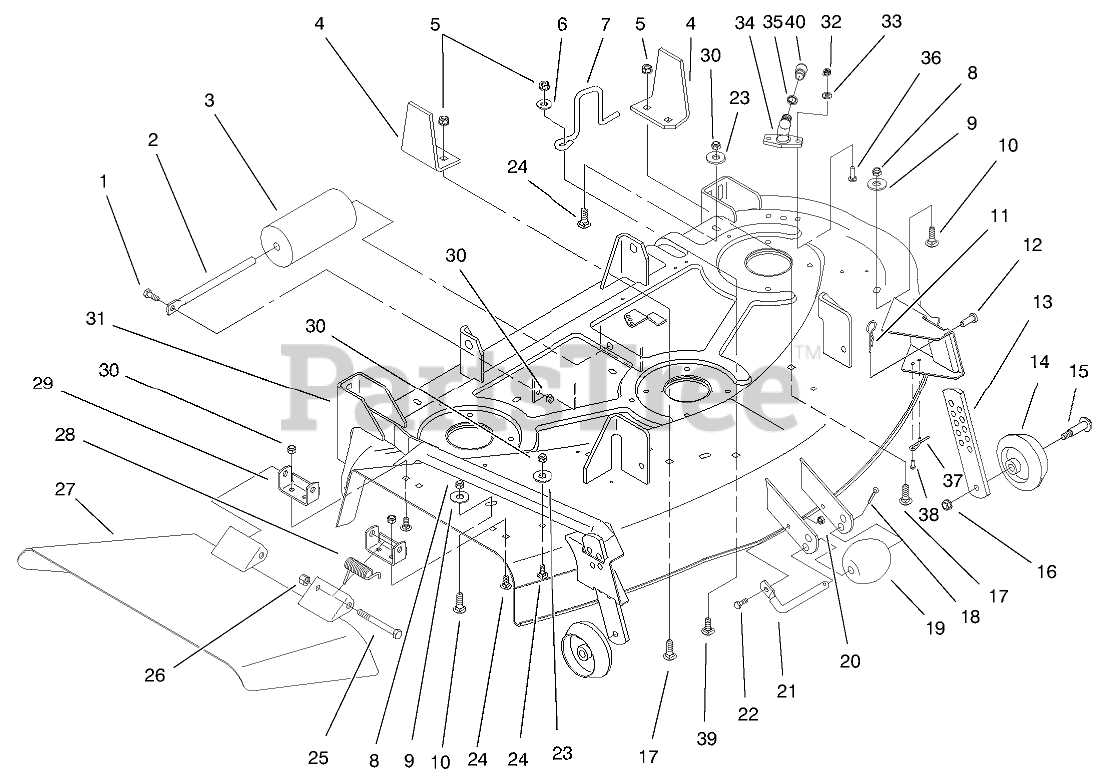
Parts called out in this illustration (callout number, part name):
1	SCREW-HH
2	ROD-ROLLER
3	ROLLER-DECK
4	Bracket Guide
5	NUT-LOCK, NI
6	WASHER
7	GUIDE-BELT
8	NUT-LOCK, NI
9	WASHER-FLAT
10	SCREW-CARR
11	PIN-HAIR
12	PIN-CLEVIS
13	PLATE-GAGE, WHEEL
14	WHEEL-GAGE
15	SCREW-SHOULDER, HWH
16	NUT-LOCK, NI
17	BOLT-CARR
18	PIN-COTTER
19	ROLLER
20	NUT-LOCK, NI
21	Shaft-Roller
22	SCREW-HH
23	WASHER-FLAT
24	SCREW-CARR
25	SCREW-HH
26	NUT-HEX
27	DEFLECTOR ASM
28	SPRING
29	BRACKET-PIVOT
30	NUT-LOCK, NI
31	Deck ASM w/Decals
32	NUT-LOCK, NI
33	WASHER-FLAT
34	FITTING-WASHOUT
35	O-RING
36	BOLT-CARR
37	SPRING-GAGE, WHEEL
38	SCREW-HWHTF
39	SCREW-CARR
40	CONNECTOR-HOSE
